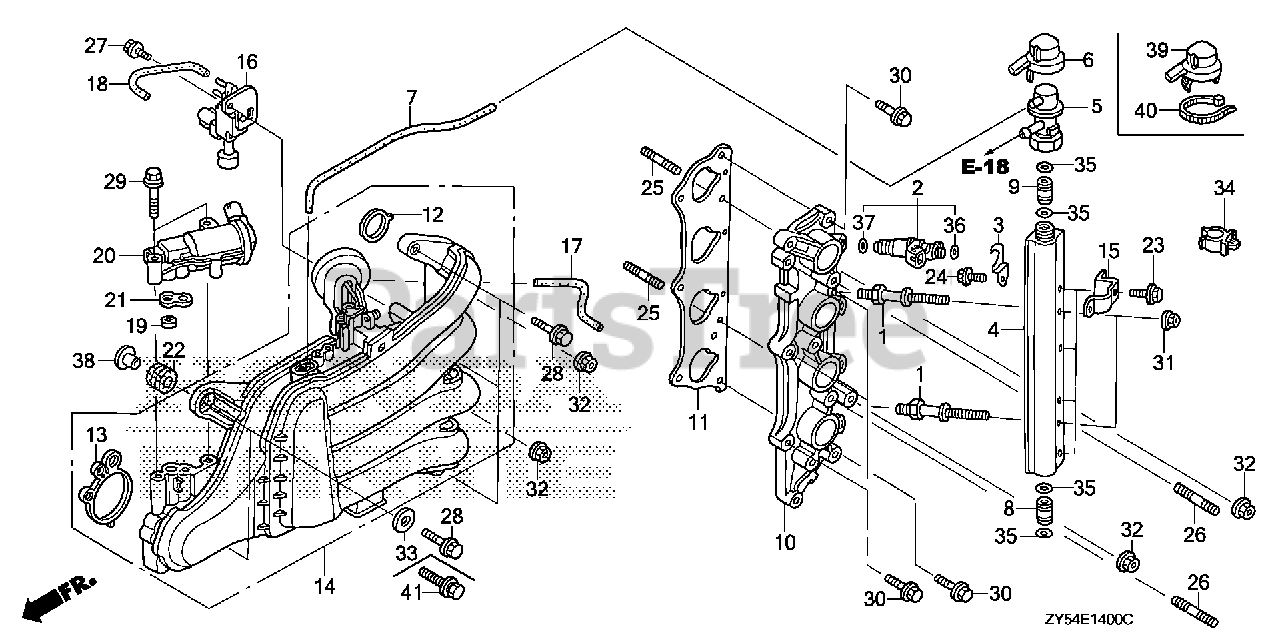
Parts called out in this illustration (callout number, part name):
1	BOLT, FUEL PIPE
2	INJECTOR ASSY., FUEL
3	CLIP, INJECTOR
4	LINE, FUEL
5	REGULATOR ASSY., PRESSURE
6	CAP, REGULATOR
7	TUBE, PRESSURE REGULATOR CONTROL
8	JOINT, FUEL PIPE
9	JOINT, FUEL PIPE
10	BASE, INJECTOR *NH8* (DARK GRAY)
11	GASKET A, INJECTOR BASE
12	GASKET, IN. MANIFOLD
13	GASKET, THROTTLE BODY
14	MANIFOLD, IN.
15	BRACKET A, HARNESS CLIP
16	VALVE ASSY., AIR BYPASS
17	TUBE, DIAPHRAGM
18	TUBE, BYPASS SOLENOID
19	FILTER, ELECTRONIC AIR CONTROL VALVE (TOYO ROKI)
20	VALVE ASSY., ELECTRONIC AIR CONTROL
21	GASKET, ELECTRONIC AIR CONTROL VALVE
22	RUBBER, FR. CARRIER CUSHION
23	BOLT, FLANGE (6X14)
24	BOLT, FLANGE (6X10)
25	BOLT 2, STUD (8X25)
26	BOLT, STUD (8X32)
27	BOLT, FLANGE (5X12)
28	BOLT, FLANGE (8X35)
29	BOLT, FLANGE (8X45)
30	BOLT, FLANGE (8X25)
31	NUT, FLANGE (6MM)
32	NUT, FLANGE (8MM)
33	WASHER, PLAIN (8MM)
34	CLIP, FUEL TUBE (14) (NOT AVAILABLE)
35	O-RING (7.8X1.9) (ARAI)
36	O-RING (7.47X3.6)
37	O-RING (7.45X3.61) (NOK)
38	COLLAR (8.5X14.5)
39	CAP, REGULATOR
40	BAND, HARNESS
